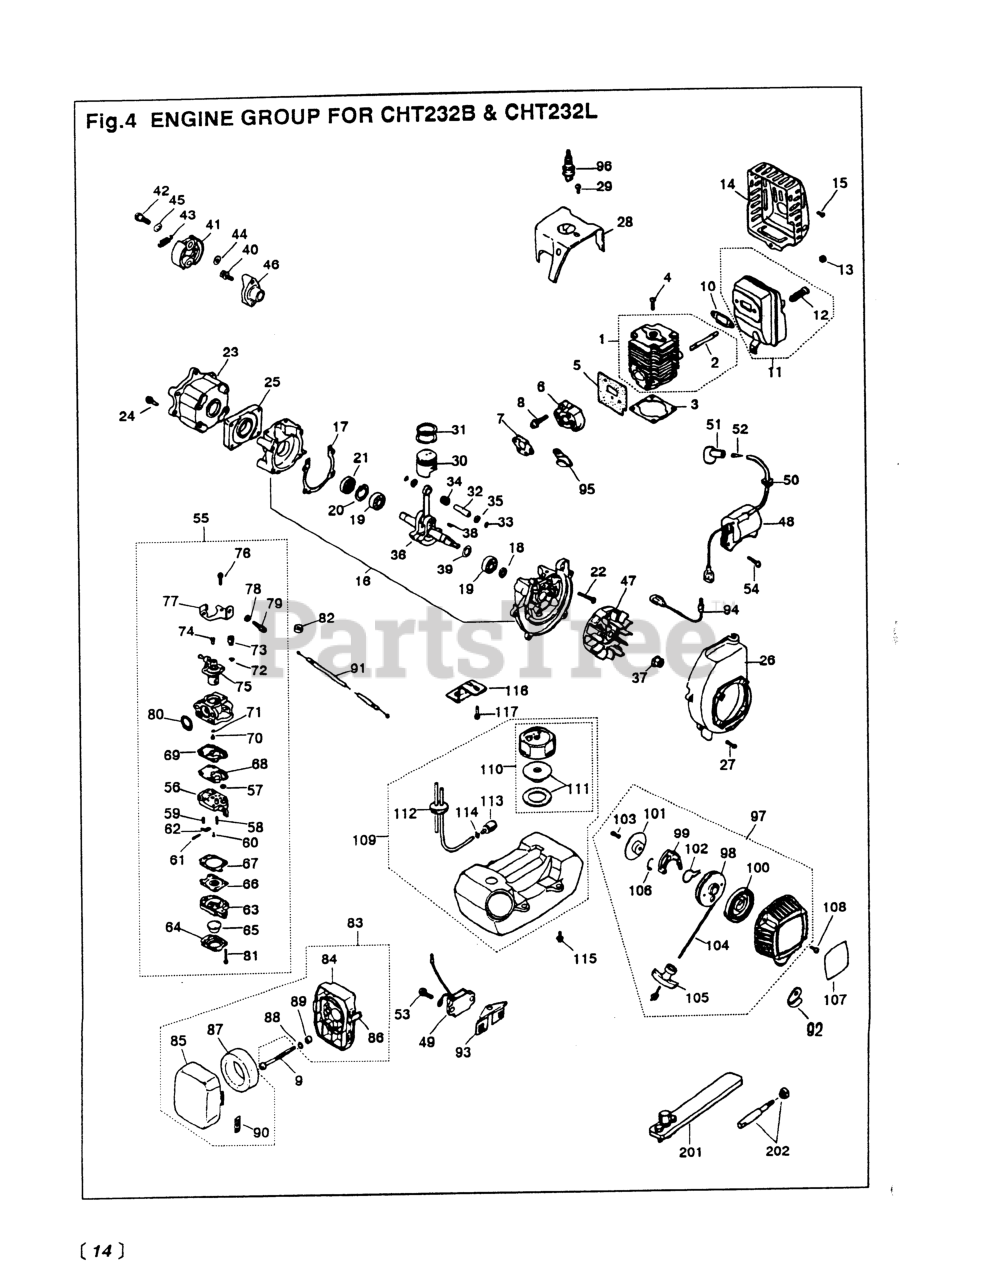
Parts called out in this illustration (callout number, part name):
1	CYLINDER-C
2	STUD
4	SCREW, M5 X 16
6	INSULATOR
9	SCREW, M5 X 55
11	MUFFLER ASSEMBLY
12	ARRESTER (RPLS 5850-15140)
13	NUT
18	SEAL, OIL
19	BEARING
20	RING, SNAP, M28 x 1.2
21	SEAL, OIL (RPLS 1140-21220)
22	SCREW, M5 x 30(RPLS 0263-00530
23	CASE, CLUTCH
26	COVER (REPLACES -31101)
27	SCREW, M4 x 14
28	COVER, CYLINDER
30	PISTON (USE 5600-41111)
31	RING, PISTON (RPLS 1850-41210)
32	PIN, PISTON 5x8x26
35	WASHER
38	KEY
40	BOLT, M6 x 14(RPLS 0224-00614)
42	BOLT
44	WASHER, FLAT (USE 182303)
45	WASHER (RPLS -51241)
46	PLATE, CLUTCH
49	UNIT
52	SPRING
53	SCREW, M5 X 12
54	SCREW, M4 x 20
55	CARBURETOR (NLA) (RPLS -81000)
56	BODY, PUMP
58	VALVE, INLET
60	SCREW, METERING LEVER PIN
61	PIN, METERING LEVER
62	LEVER
63	BODY, PURGE
64	COVER, PUMP
65	PUMP, PRIMING
66	DIAPHRAGM (USE 4810-81260)
67	GASKET, DIAPHRAGM
68	DIAPHRAGM
69	GASKET, PUMP
70	JET
71	RING, O
72	RING
73	SWIVEL
75	VALVE ASSEMBLY
76	SCREW
77	BRACKET
78	NUT, CABLE ADJUSTER
79	SCREW, CABLE ADJUSTER
80	RING, PACKING
81	SCREW
82	CAP, CABLE END
83	CLEANER ASSEMBLY
84	BODY
85	COVER
89	SLEEVE (USE 1918-82170)
90	LABEL
91	CABLE
92	CLAMP
93	BRACKET (RPLS -72240)
94	CORD (NO LONGER AVAILABLE)
95	CLAMP
97	STARTER ASSEMBLY
99	RATCHET
101	PLATE (NLA) (RPLS -75240)
102	SPRING, FRICTION
103	SCREW (USE -75261)
105	KNOB
106	SPRING
108	SCREW, M4 X 12
111	VALVE COMPLETE
112	PIPE ASSEMBLY
113	5500-85400 (RRLS. 1750-85300)
114	CLIP (REPLACES 2841-31280)
116	BRACKET-NO LONGER AVAILABLE
202	(H) ROD ASSY
